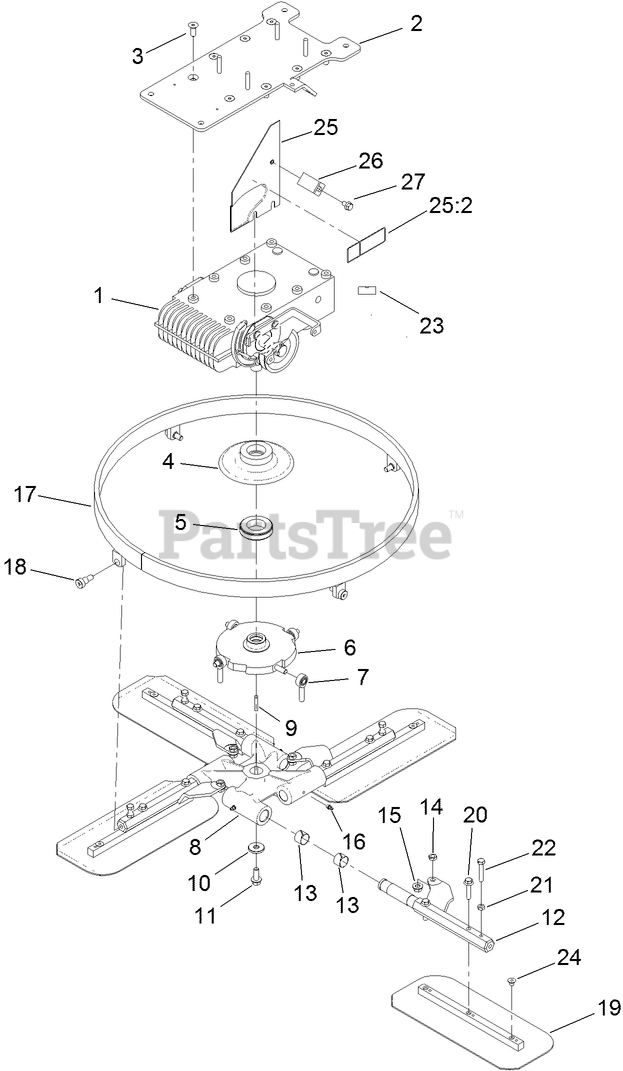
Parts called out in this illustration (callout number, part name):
1	GEARBOX ASM
2	ENGINE BASE ASSEMBLY
3	SCREW
4	COVER-PLATE, THRUST
5	BEARING-BALL
6	PLATE-TILT
7	BEARING-END, ROD
8	SPIDER-4 ARM
10	WASHER-FLAT
11	SCREW-HHF
12	ARM
13	BUSHING-SLEEVE, NYLON
14	NUT-HJ
15	NUT-FLANGE, LOCK
16	FITTING-GREASE
17	ROTATING-RING
18	SCREW-HSBH
19	BLADE-COMBINATION
20	SCREW-HHF
21	NUT-JAM
22	SCREW-HH
23	ROD-PIVOT, CABLE
24	CARPLUG-RED
25	REAR BELT GUARD ASM
25:2	DECAL-WARNING
26	GUIDE-BELT
27	SCREW-FLANGE
